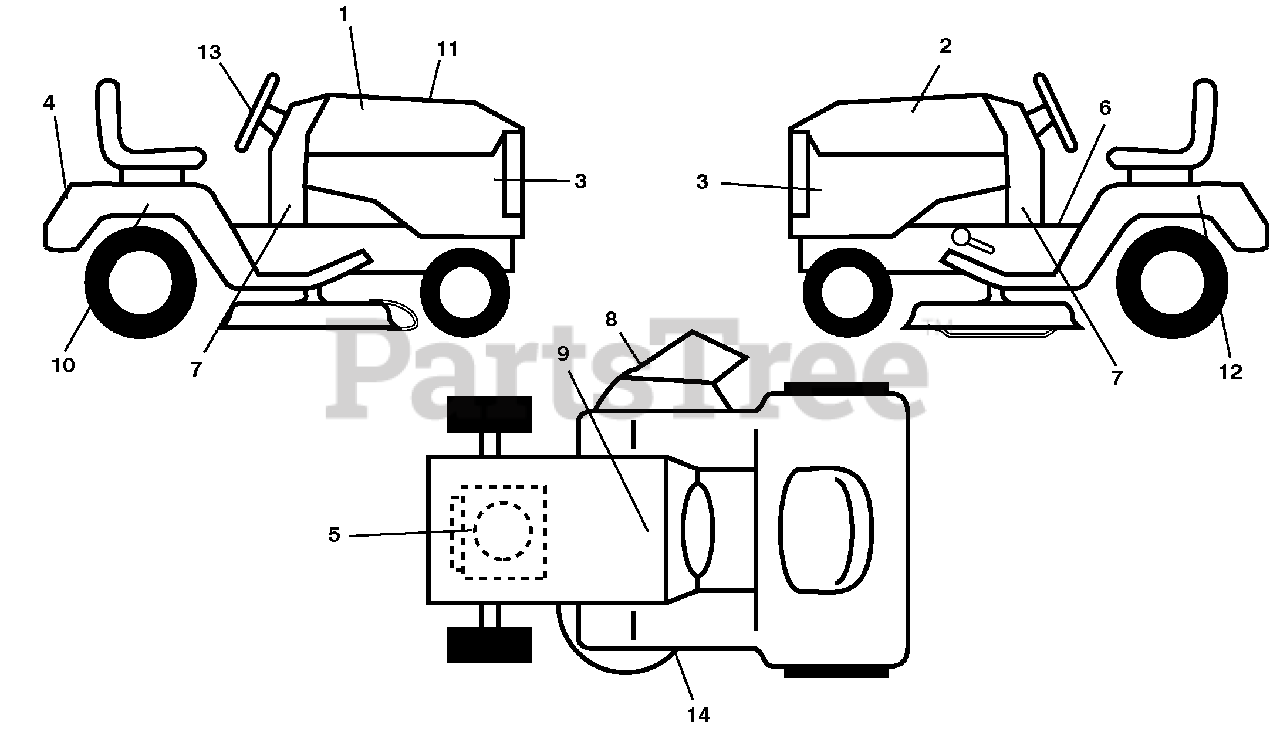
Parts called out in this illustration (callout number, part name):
1	Decal, Hood RH
2	Decal, Hood LH
3	Decal, Side Panel
4	Decal, Fender
5	Decal, Engine
6	Decal, Fender
7	Decal, Lower Dash
8	Decal, Warning
9	Decal, Battery Dnge/Poi
10	Decal, Fender Side RH
11	Decal, Replacement
12	Decal, Fender Side LH
13	Decal, Steering Wheel
14	Decal, Mower Schematic
14	Pad, Footrest, RH
14	Decal, Bypass
14	Pad, Footrest, LH
14	Manual, Operator's (Eng/French)
14	Manual, Parts
